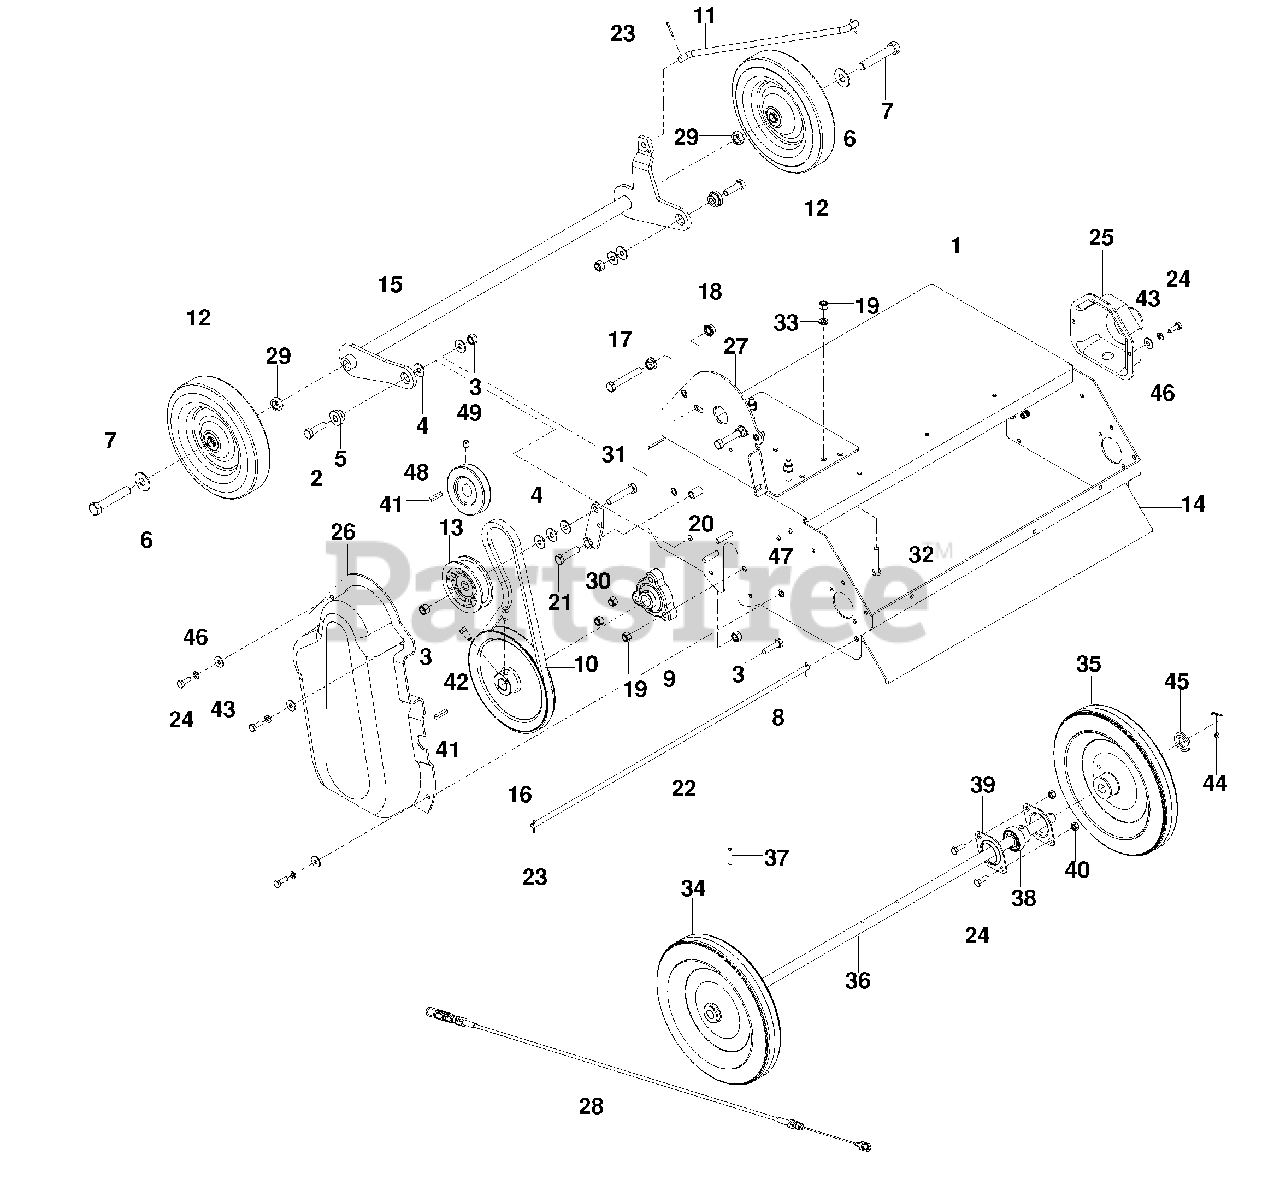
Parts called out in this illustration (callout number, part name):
1	BODY, ORG
2	HCS 3/8-16 x 1 1/4
3	NUT 3/8-16 NYLOC
4	WASHER 5/16
6	WASHER, 1/2
7	HCS 1/2-13 x 2 3/4
8	HCS 5/16-18 x 1 1/4
9	BEARING FLANGE C.I.
12	WHEEL, 8 x 1.75
13	IDLER PULLEY, HYDRO'S
15	AXLE, FRONT
16	PULLEY, 7"
17	HCS 3/8-16 x 2 1/2
18	NUT 3/8-16 WHIZLK
19	NUT 5/16-18 NYLOC
21	HCS 3/8-16 x 1 1/2
23	PIN COTTER 3/4
24	HCS 1/4-20 x 3/4
25	SHAFT GUARD
26	BELT GUARD
27	BACKING PLATE
29	NUT 1/2-13 JAM
30	IDLER, ARM
31	HCS 3/8-16 x 2
32	HCS 5/16-18 x 1 3/4
33	LOCKWASHER 5/16
34	WHEEL, 10x1.75 DRILLED
35	WHEEL, 10x1.75 w/ BUSHING
37	PIN ROLL 1/4 x 11/8
38	BEARING 5/8 w/ COLLAR
39	BRG FLANGETTE 5/8 2 BOLT
40	NUT 1/4-20, NYLOC
41	KEY 1/4 SQ x 11/8
42	SCREW 5/16-18 x 5/8 SET
43	WASHER 1/4
44	COTTER PIN 1/8 x 1 1/4
45	WASHER 5/8 SAE
46	WASHER 1/4 SPLIT LOCK
47	KNURLED INSERT 1/4-20
48	PULLEY, 3"
49	SCREW 5/16-18 x 3/8, SET KRL
